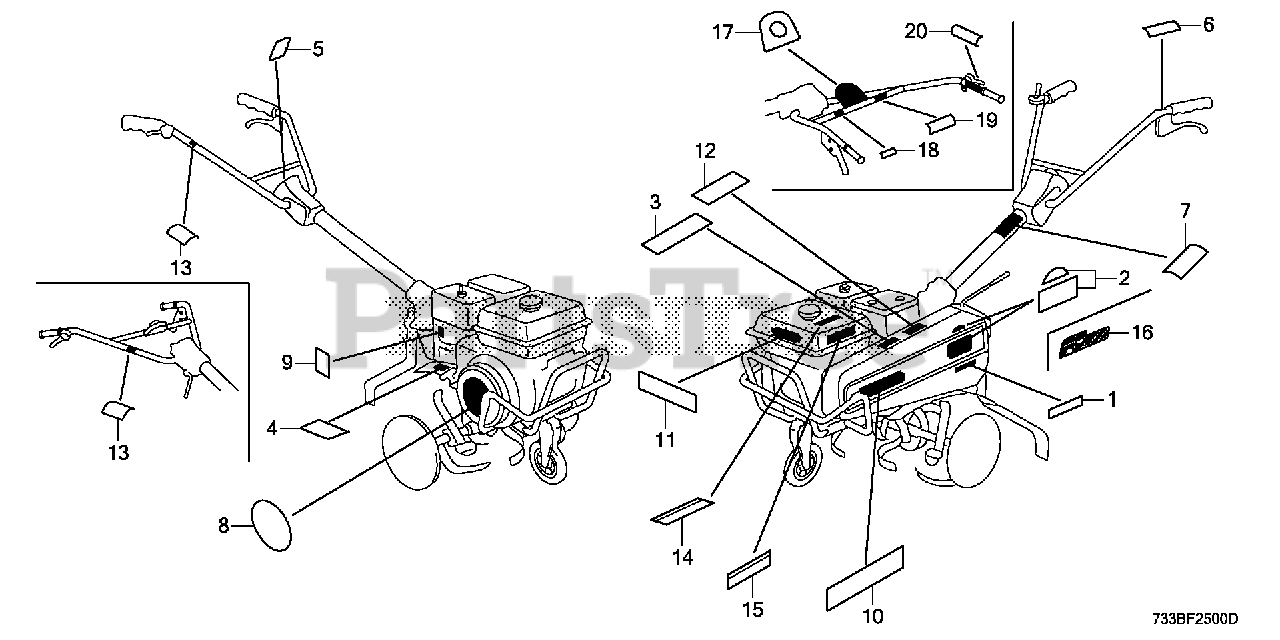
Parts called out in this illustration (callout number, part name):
1	MARK, L. STRIPE (FC600)
2	MARK, SIDE EMBLEM
3	LABEL, BELT WARNING (ENGLISH)
4	MARK, TINE DANGER
5	MARK, ENGINE SWITCH (ENGLISH)
6	MARK, CLUTCH INDICATION (US)
7	LABEL, OPERATOR WARNING (ENGLISH)
8	PLATE, EMBLEM
9	MARK, CHOKE
10	EMBLEM (13) (HONDA)
11	MARK, HONDA EMBLEM (12 (HONDA)
12	LABEL, HEAT WARNING (ENGLISH)
13	MARK, HOLD POSITION
15	LABEL, SPARK WARNING
